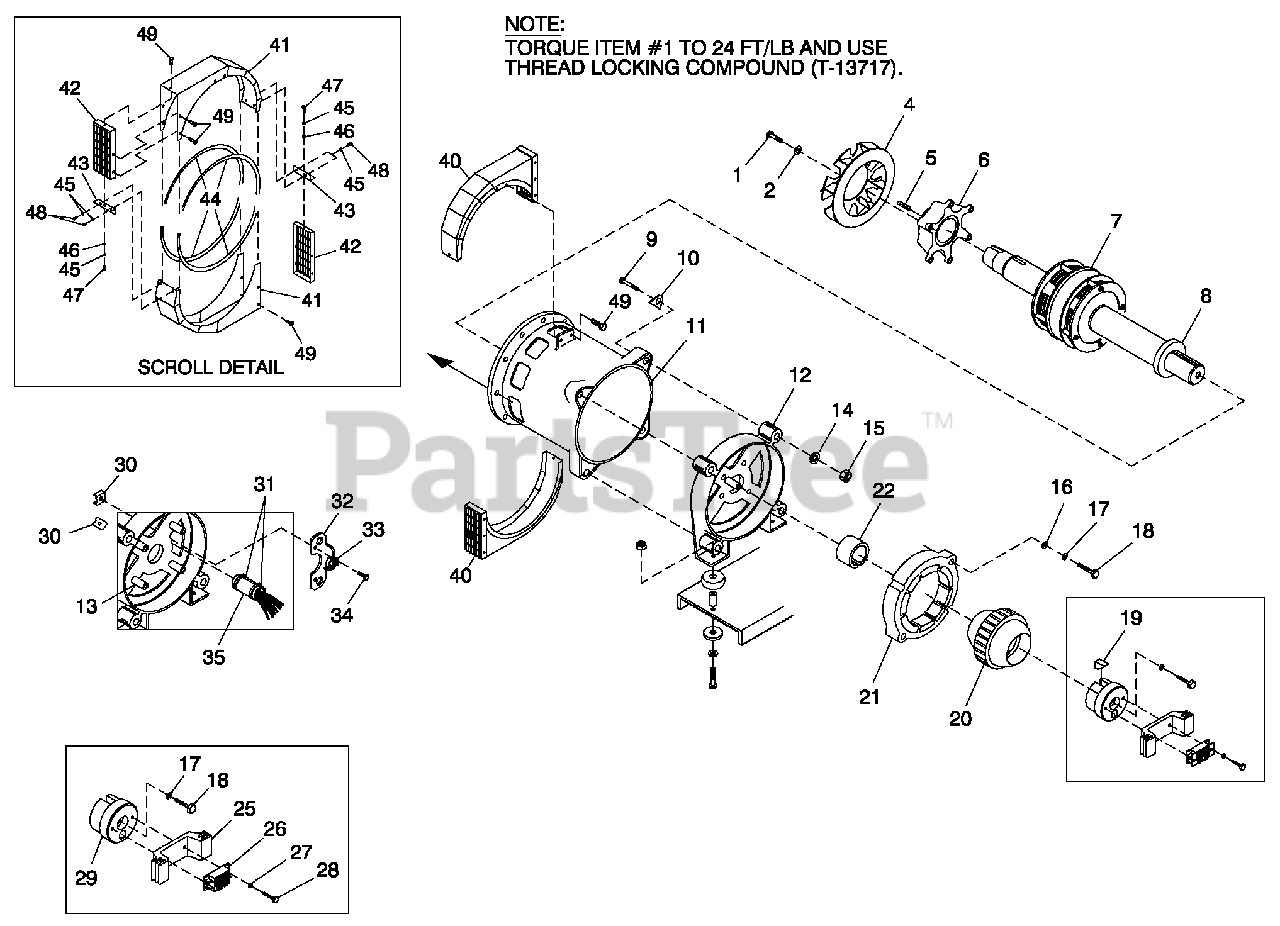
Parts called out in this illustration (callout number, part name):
1	SCREW HHC M8-1.25 X 20 G10.9
2	WASHER LOCK M8-5/16
4	FAN SAE ALTERNATOR (G/B)
5	KEY SQ 3/8X1-9/16 STEEL
6	HU B DRIVE 390 SAE G B
7	RTR 390 100K B3 G B SAE TECHUM
8	BEARING BALL 6212 SEALED
9	SCREW HHC M14-2.0 X 140 G8.8
10	WASHER 390 SAE ALT.
11	STR-390-80LB3 SAE
12	CARRIER REAR BRG 15"
13	PIN DOWEL 1/2 X 1-1/4
14	WASHER LOCK M14
15	NUTHEXM14-2.0 G8 YEL CHR
16	WASHER FLAT M12
17	WASHER LOCK M12
18	SCREW HHC M12-1.75 X 60 G10.9
19	KEY SQ 3/8 X 3-1/4 STEEL
20	ASSY EXCITER 2.00" STK
21	EXITER FIELD 2" LG SPD CONN
22	COLLAR SLIP FIT 390 MM
25	BRIDGE SUPPORT DIODE 15"
26	ASSY BRIDGE RECTIFIER
27	WASHER SHAKEPROOFINT #8
28	SCREW HHM #8-32X7/8
29	CAP END ROTOR 390MM
30	PLATE NUT
31	TIE WRAP UL 14.6 X.14 NATL
32	BRACKET-STATORWIRE
33	CLAMP HOSE #36 1.88-2.7
34	SCREW HHC 5/16-18 X 1-1/4 G5
35	SLEEVE RU BBER
40	ASSY SCROLL 390 SAE
41	SHROUD ALT SHEET METAL
42	SCREEN SHROUD SAE
43	BRKT TENSIONER SAE SCROLL
44	TRIM VINYL BLACK 1/8 GP
45	WASHER LOCK M6-1/4
46	WASHER FLAT 1/4-M6 ZINC
47	SCREW HHC M6-1.0X 25 G8.8
48	SCREW HHC M6-1.0X 16 G8.8
49	SCREW SWAGE 1/4-20 X 1/2 ZYC
